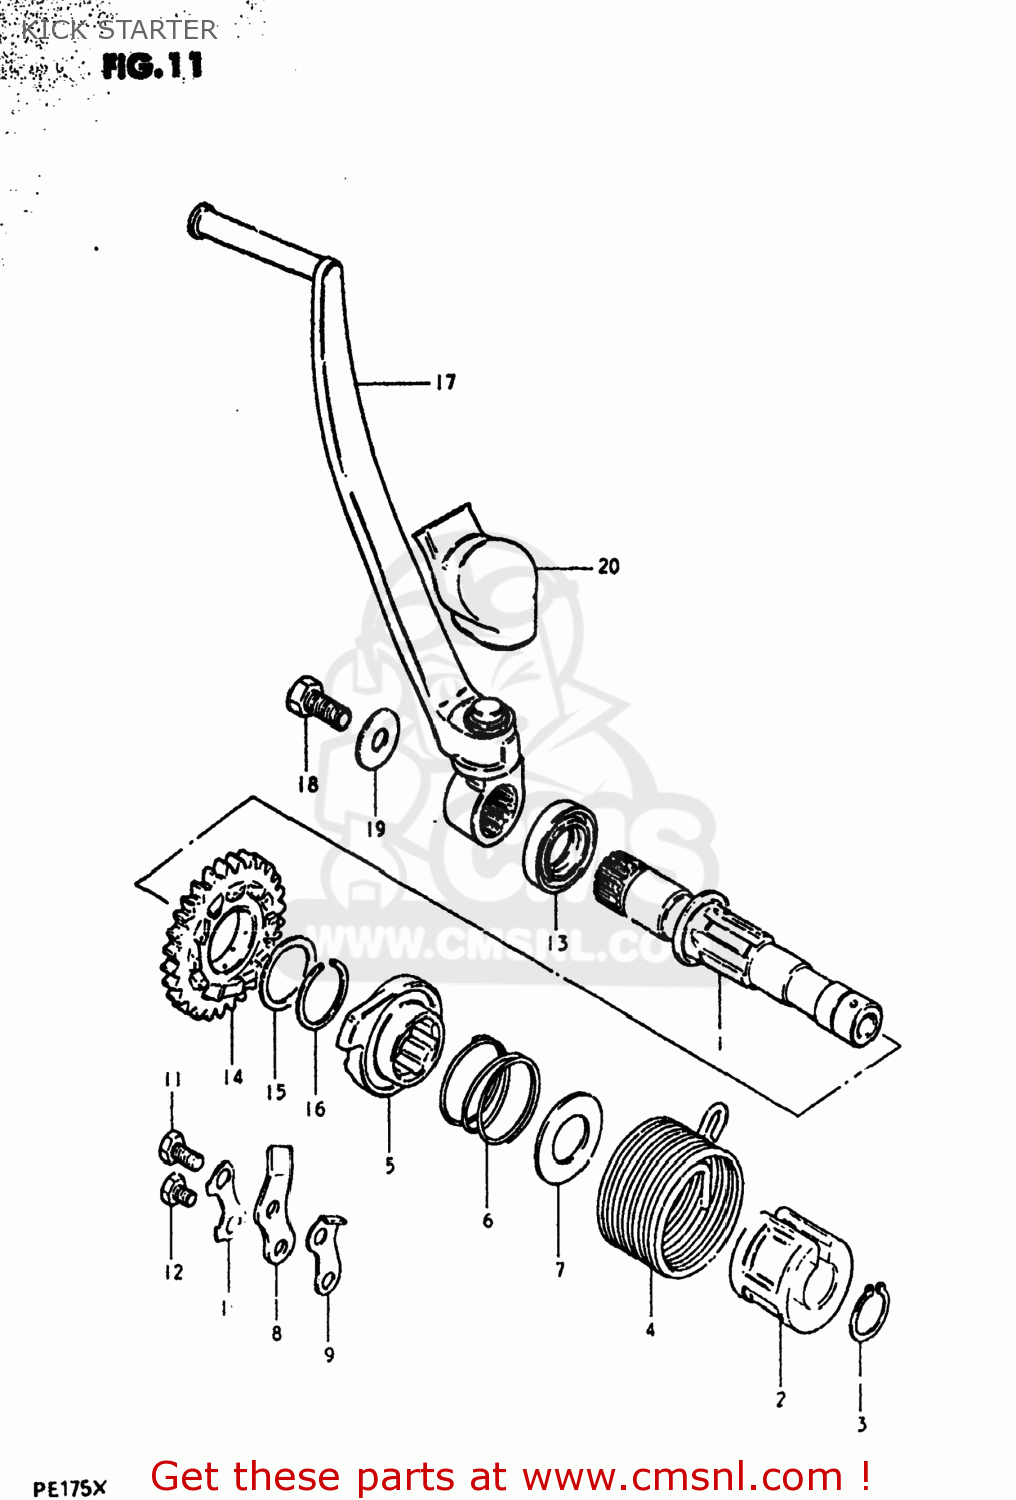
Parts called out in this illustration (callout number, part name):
1	SHAFT,KICK STARTER
2	GUIDE,KICK STARTER SFT SPRING
3	CIRCLIP
4	SPRING
5	STARTER,KICK
6	SPRING
7	WASHER
8	GUIDE,KICK STARTER
9	STOPPER,KICK STARTER
10	WASHER
11	BOLT, UPPER
12	BOLT
13	SEAL,OIL(20X27X5)
14	GEAR,KICK STARTER DRIIVE
15	SHIM
16	CIRCLIP
17	LEVER ASSEMBLY,KICK STARTER
18	BOLT
19	WASHER(8.2X23X3.2)
20	COVER,KICK LEVER JOINT
